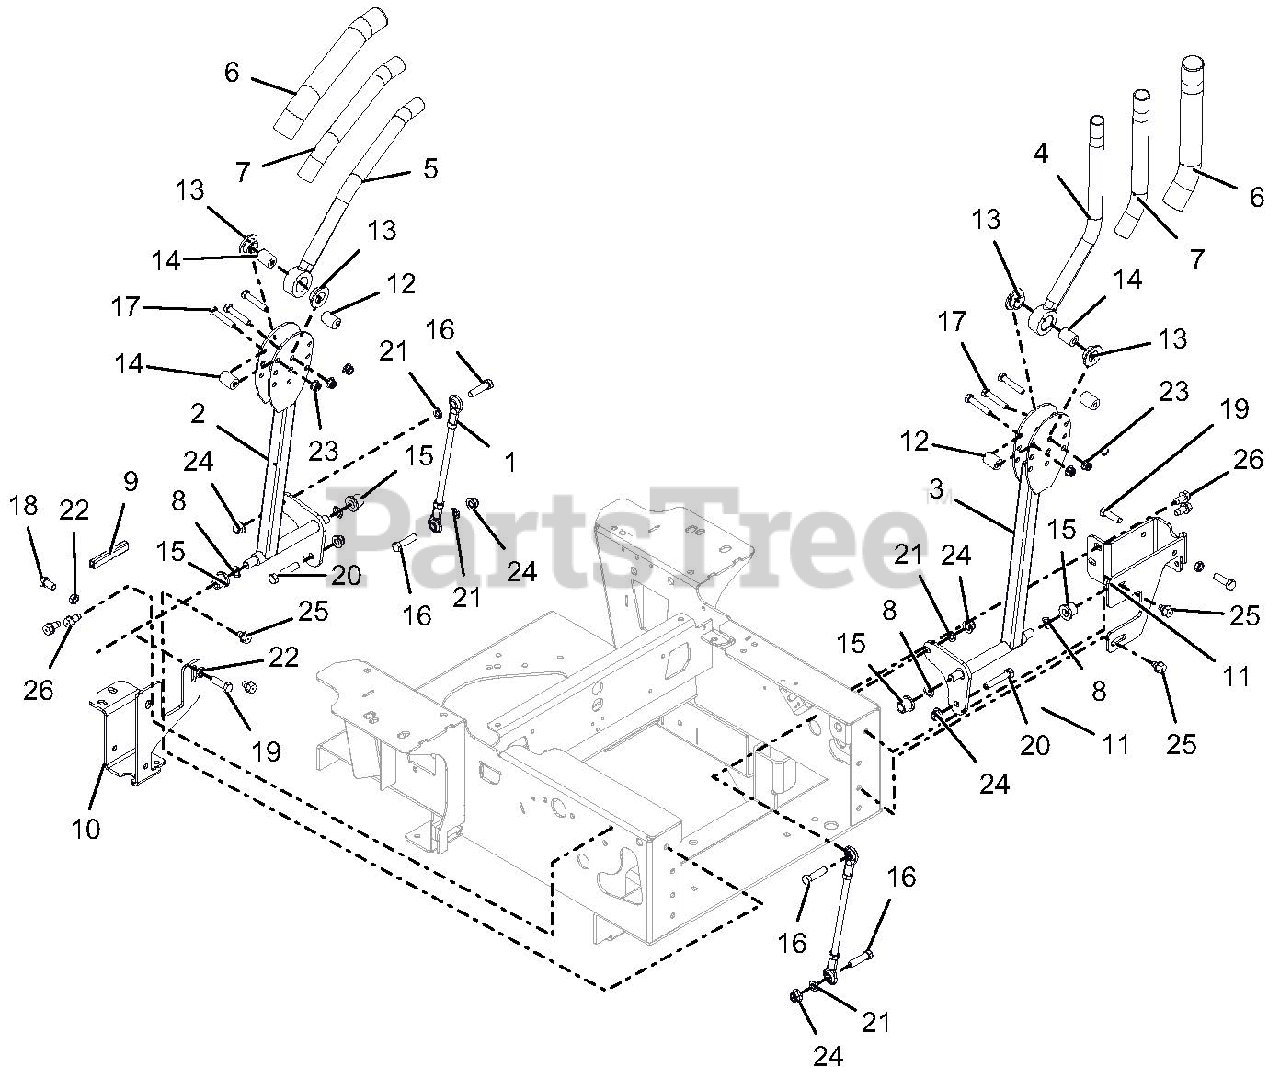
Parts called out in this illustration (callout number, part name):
1	ASM, STEERING LINKAGE
2	WLDMT, PT/PT100 CONTROL ARM-BLACK
3	WLDMT, LH PT/PT100 CONTROL ARM
4	WLDMT, LH HANDLE
5	WLDMT, RH HANDLE
6	GRIP, HANDLEBAR
7	TUBE, .88ID X 1.00OD X 10.25
8	WAVE WASHER .531X.781X.125 FH
9	STRIP, COWL - 1.50 LG
10	BRKT, RH STEERING STOP-RED
11	BRKT, LH STEERING STOP-RED
12	BSHG, ECCENTRIC .328 X .750 X .970
13	BSHG, FLANGE .762 X 1.48 X .44 NYLON
14	SPACER, .328 X .76 X 1.01
15	BHSG-FLG .500X.750X.750X.125
16	BLT-HEX .38-16X1.50 GR5 YWZC
17	BLT-HEX .31-18X1.75 GR5 YWZC
18	BLT-HEX .38-16X.75 GR5 YWZC
19	BLT-HEX .38-16X1.25 GR5 YWZC
20	BLT-HEX .38-16X2.00 FTH GR5 YWZC
21	WSHR-LK .38X.094 REG YWZC
22	NUT, JAM .375-16 YWZC
23	NUT-LK-NYL-FLG .31-18 YWZC
24	NUT-LK-NYL-FLG .38-16 YWZC
25	SCR-TAP .38-16X.50 HWH TR YWZ
26	SCR-TAP .38-16X.75 HWH TR YWZ
